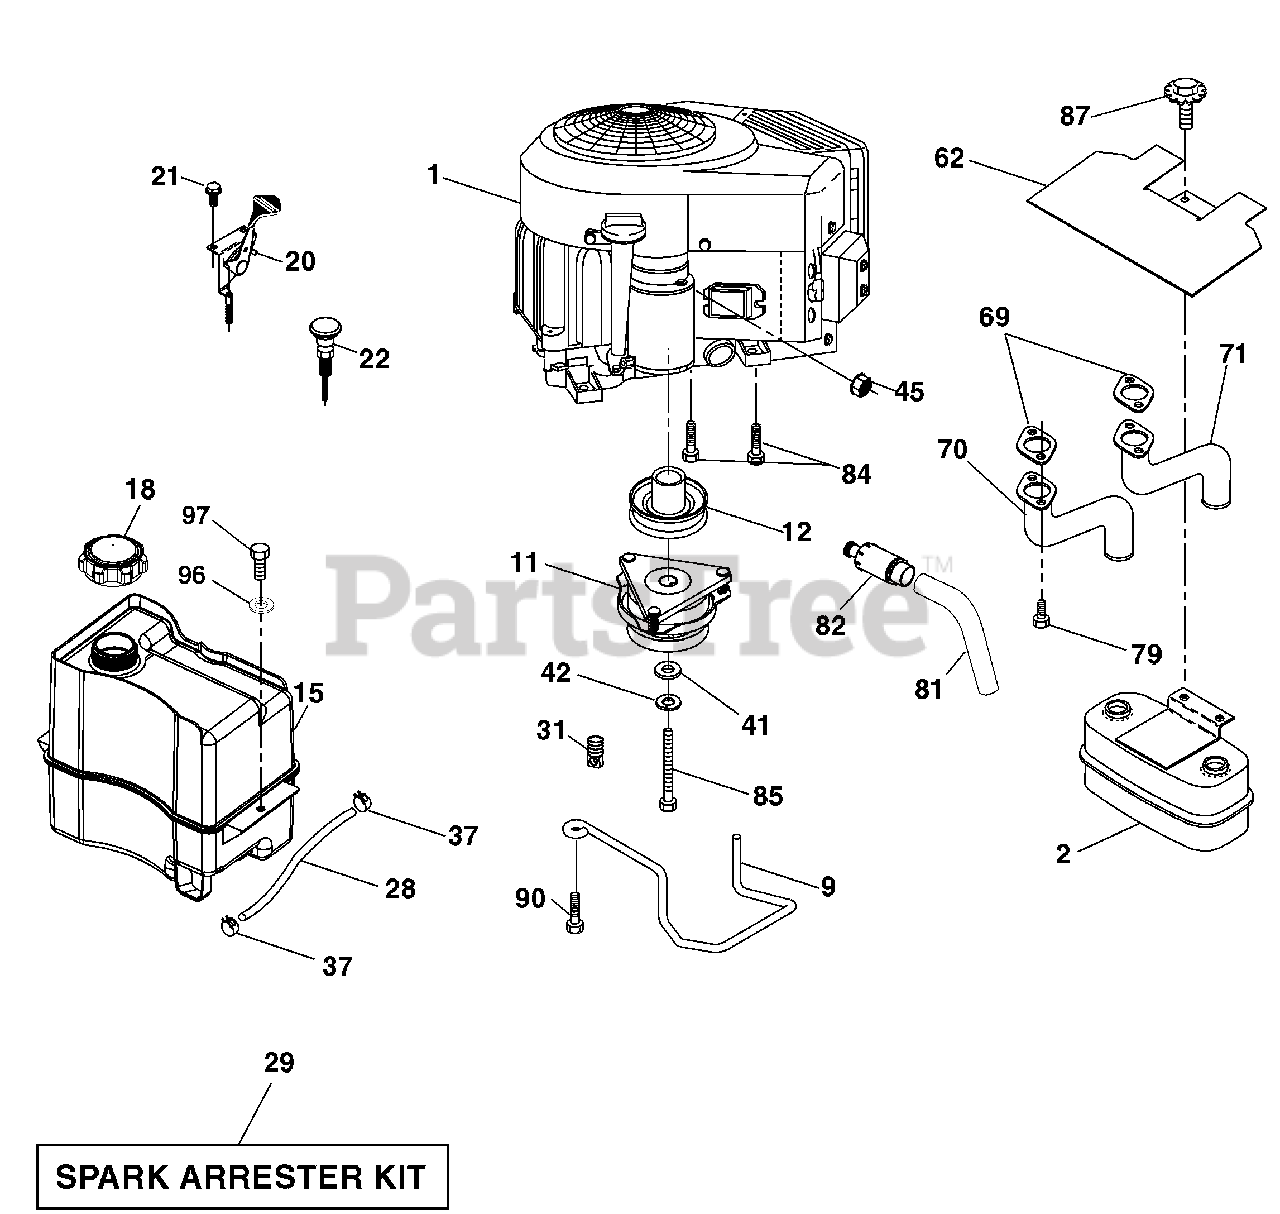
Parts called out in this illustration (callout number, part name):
9	Keeper Belt Engine
11	Clutch electric
12	Pulley Engine
15	Tank Fuel
18	Cap Asm
20	Control Throttle
21	Screw #10 x .750 BOS Thread
22	Choke Control
28	Fuel Line
29	Spark Arrester Kit
31	Clip Push-in Hinged
37	Clamp Hose
41	Washer 1-1/2 OD x 15/32 ID x .250
42	Washer Lock 7/16
45	Nut Keps Hex 1/4-20 unc
62	Heat Shield
70	Tube Exhaust
71	Exhaust Tube
79	Screw Socket HP 5/16-18 x 1
81	Tube Drain Oil Easy
82	Plug Drain Oil
84	Screw 3/8-16 x 1
85	Bolt Hex 7/16-20 x 4 x Gr. 5-1.5 Thr
86	Nut M8 - 1.25
87	Bolt 5/16-18 UNC x 3/4 w/Sems
90	Screw 3/8-16 x 1
96	Washer 9/32 x 7/8 x 16 Ga.
97	Screw 1/4-20 x 3/4
